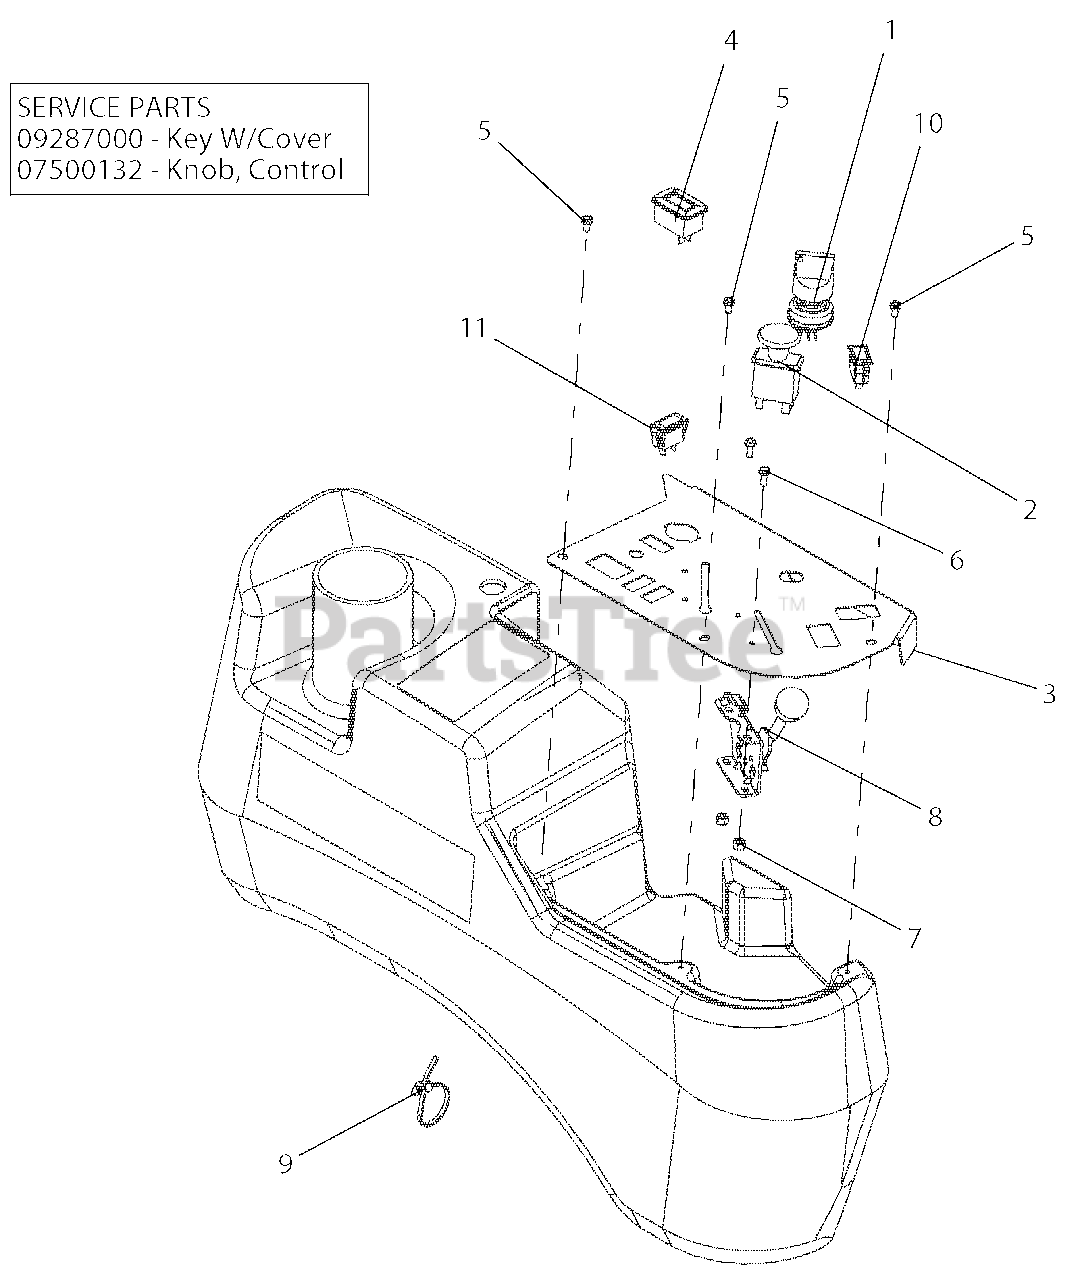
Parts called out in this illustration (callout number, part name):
1	SWITCH, IGNITION
2	SWITCH, CLUTCH
3	PANEL, CONTROL (BLACK)
4	METER, HOUR W/MAINTENANCE
5	SCR-MCH 10-24X.38 HWHSTAINLESS
6	@SCR-MCH 10-24X.50 HWH YWZC
7	NUT-LK-NYL #10-24 YWZC
8	CABLE, PRO-CONTROL THROTTLE
9	CABLE TIE W/ TREE (.25 HOLE)
10	LIGHT, INDICATOR
11	LIGHT, INDICATOR
